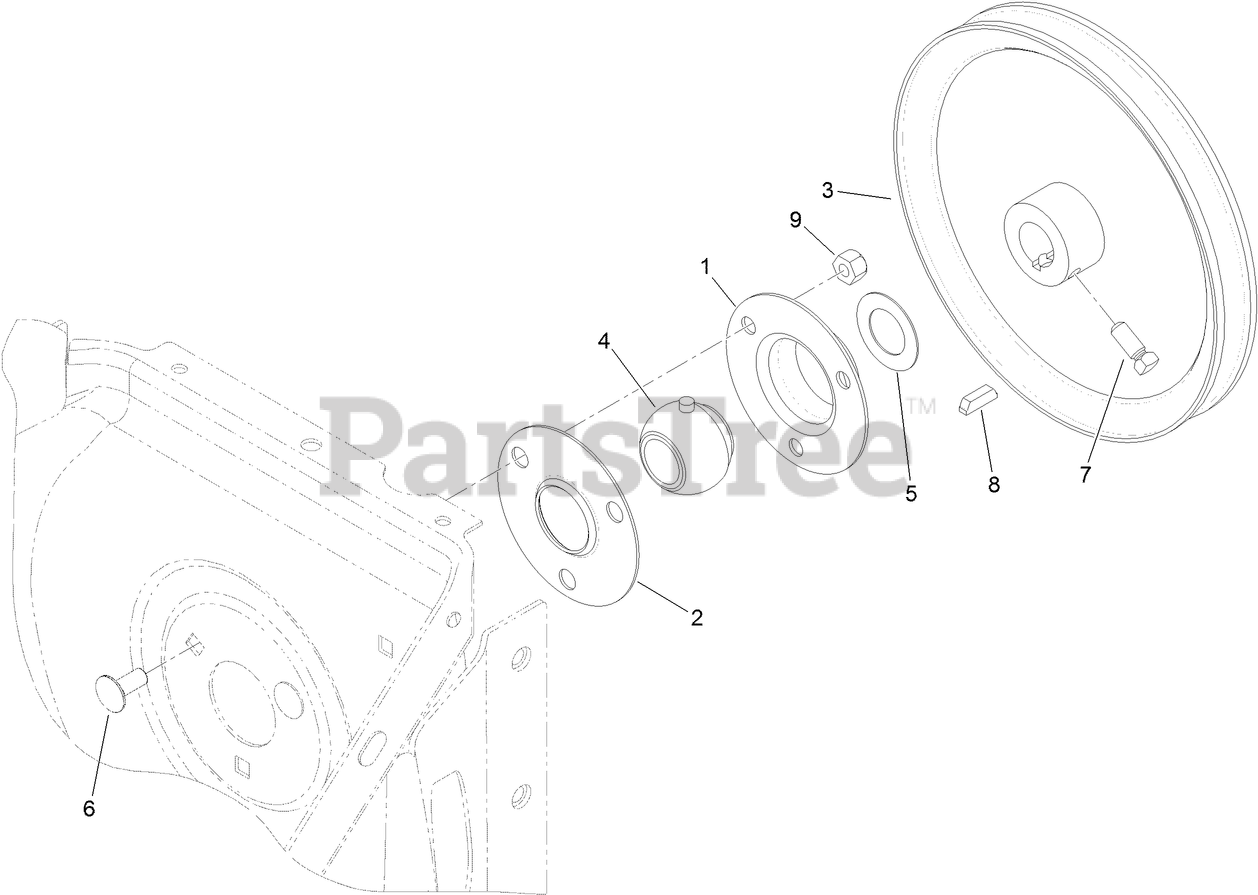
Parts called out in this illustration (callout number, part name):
1	FLANGE-CUP, BEARING
2	FLANGE-CUP, BEARING
4	BEARING-BALL
5	WASHER-THRUST
6	SCREW-CARR
7	SCREW-SET
8	KEY-WOODRUFF
9	NUT-LOCK, NI
